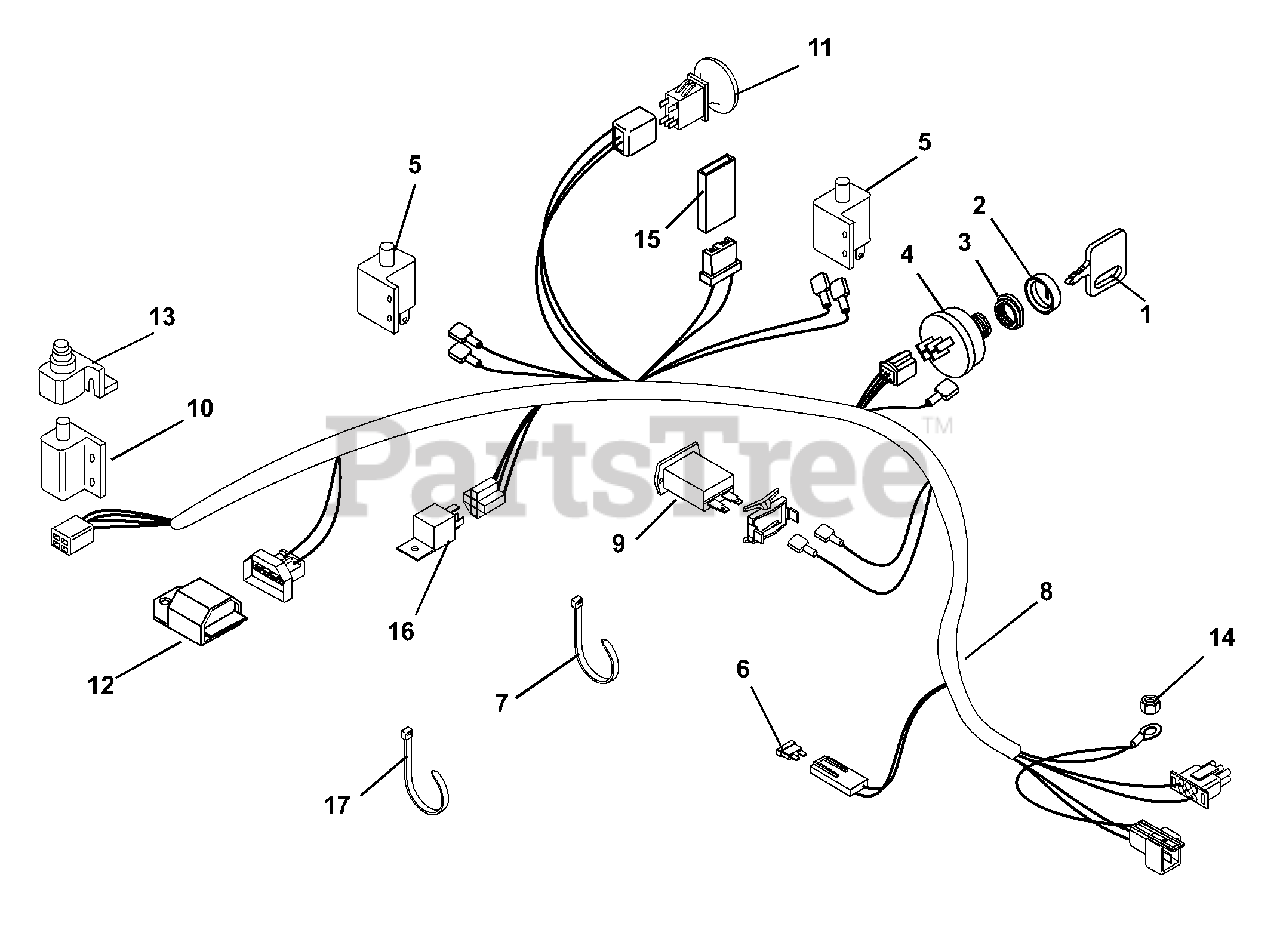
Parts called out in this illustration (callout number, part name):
1	KEY -W/CAP
2	CAP - IGNITION SWITCH
3	NUT- PANEL .562-24 GRECO
4	KEY SWITCH
5	SWITCH- DOUBLE POLE N.O./N.O.
6	FUSE-25 AMP ATC TYPE
7	CABLE TIE LG 5-1/2
8	HARNESS-WIRE HYDRO RECOIL-ERGO
9	HOUR METER - DIGITAL
10	SWITCH,INTERLOCK
11	SWITCH - PTO - NMIR
12	MODULE,INTERLOCK,RECOIL, 1201
13	BOOT, RUBBER
14	@NUT-LK-TOP-FLG .31-18 YWZC
15	DIODE, CONNECTOR SHELL
16	RELAY
17	TIE WRAP
